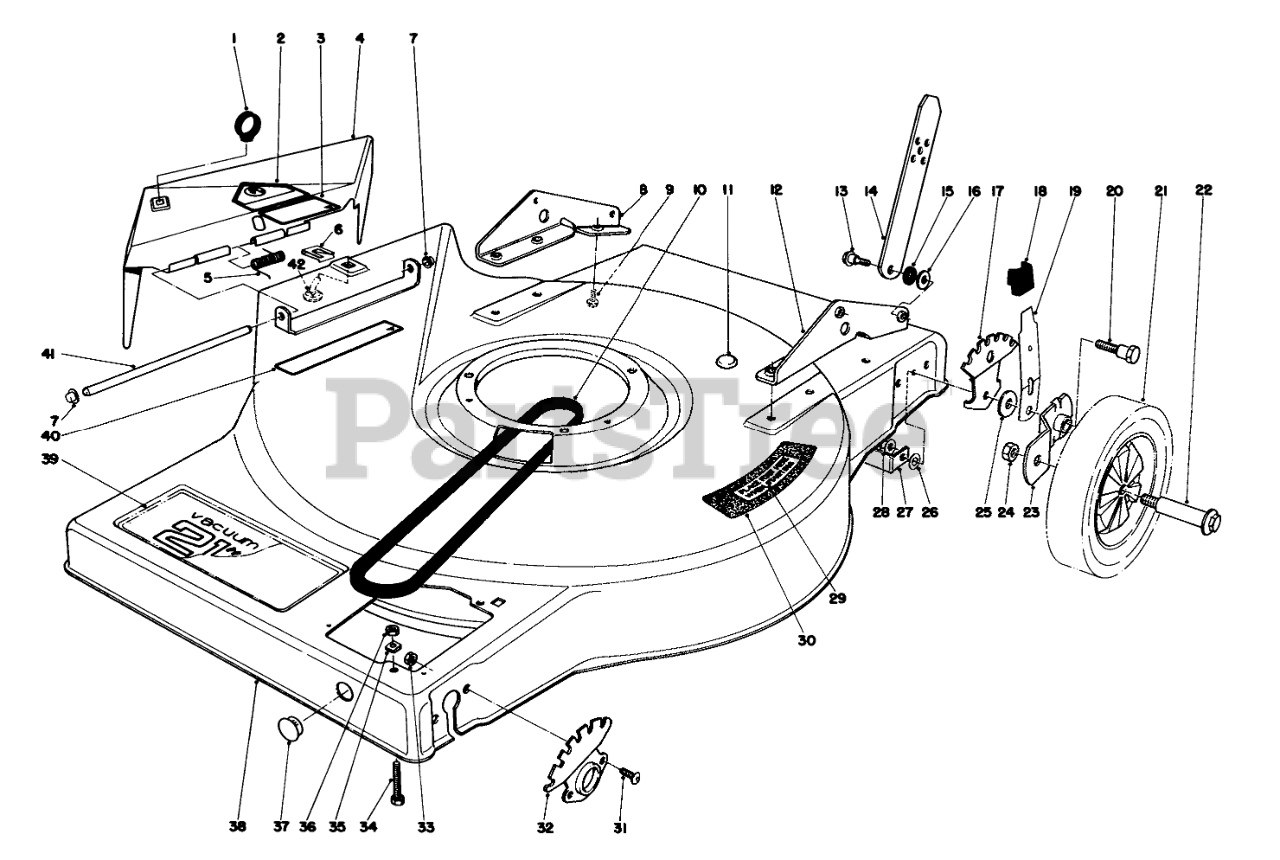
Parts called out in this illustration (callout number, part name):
1	LIFT LOOP
2	DECAL-DANGER
3	DECAL DEFLECTOR
4	Deflector (Incl. Ref. #2 & 3)
5	TORSION SPRING
6	BAG CHUTE CLIP PIN
7	PUSHNUT-CAP, WASHER
8	Bracket Handle R.H.
9	SCREW-HWHTF
10	V-BELT
12	Bracket-L.H.
13	SCREW-SHOULDER
14	Handle Latch
15	SPACER
16	WASHER-PLAIN
17	Washer
18	KNOB-ARM
19	SPRING ARM ASM
20	PIVOT SCREW
21	Wheel & Tire Assembly
22	BOLT-WHEEL
23	PIVOT ARM ASM A
24	Nut
25	PIVOT WASHER
26	WASHER
27	DECK SUPPORT
29	Decal Step Pad
30	PAD STEP
31	Capscrew-Button Hd.
32	QUADRANT S.P.
33	NUT-LOCK, CONE
34	SCREW
35	SPEED NUT
36	NUT-JAM
37	Hole Plug
38	Housing
39	Decal-Deck
40	DECAL CAUTION
41	DEFLECTOR PIVOT ROD
42	BAG CHUTE PIN
